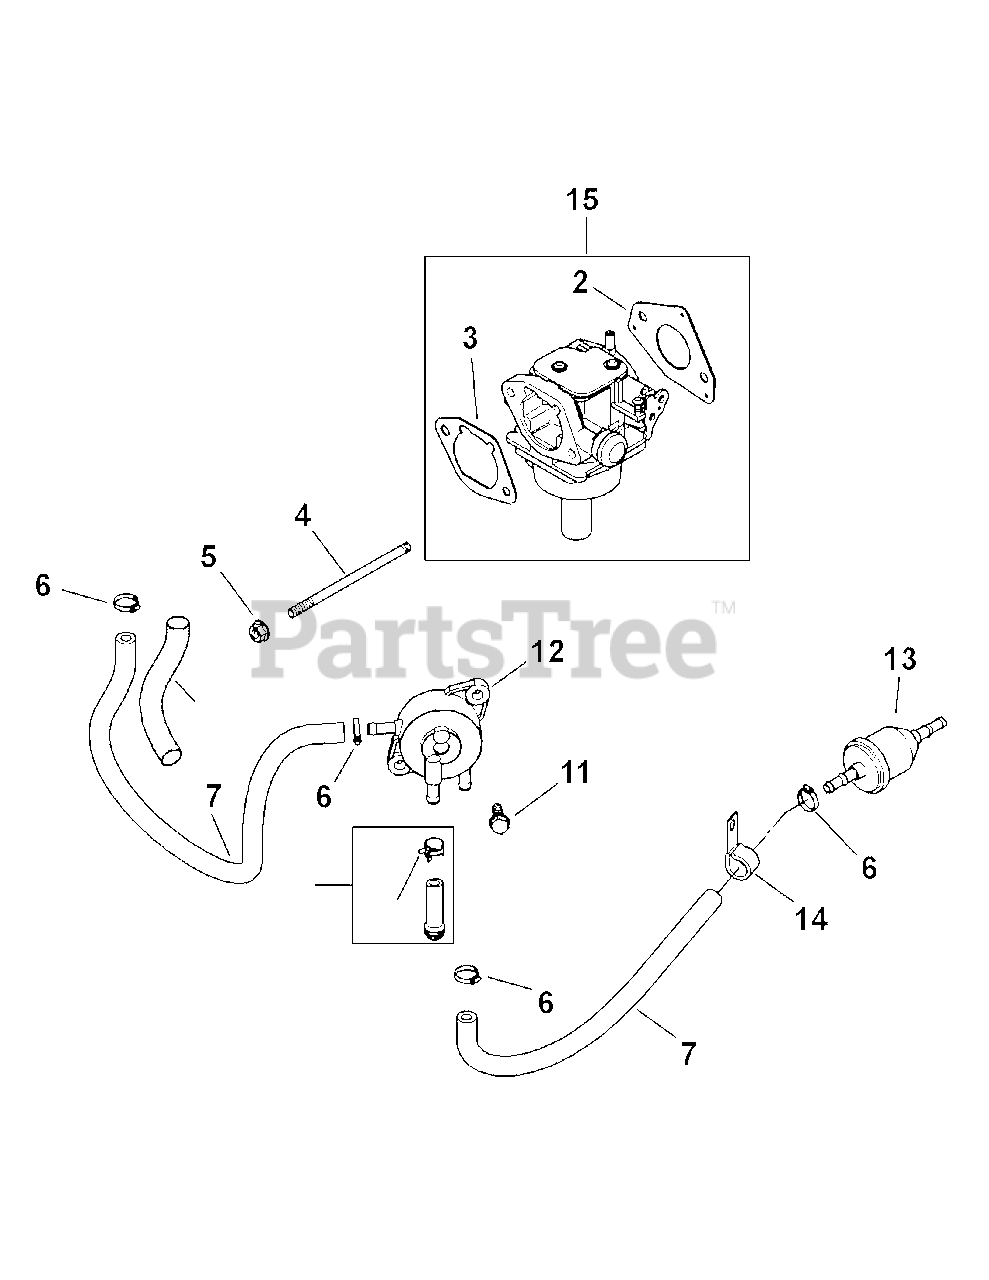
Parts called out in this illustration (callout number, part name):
2	Carburetor Gasket
3	Air Cleaner Base Gasket
4	Stud, M6 X 1.0 X 106
5	Flg. Nut, M6 X 1.0
6	Hose Clamp, 1/2
7	Fuel Line
11	Tap Screw, M6 X 1.7 X 18
13	Fuel Filter
15	Carburetor Kit, 19mm KEIHIN (Inc. 2 & 3)
